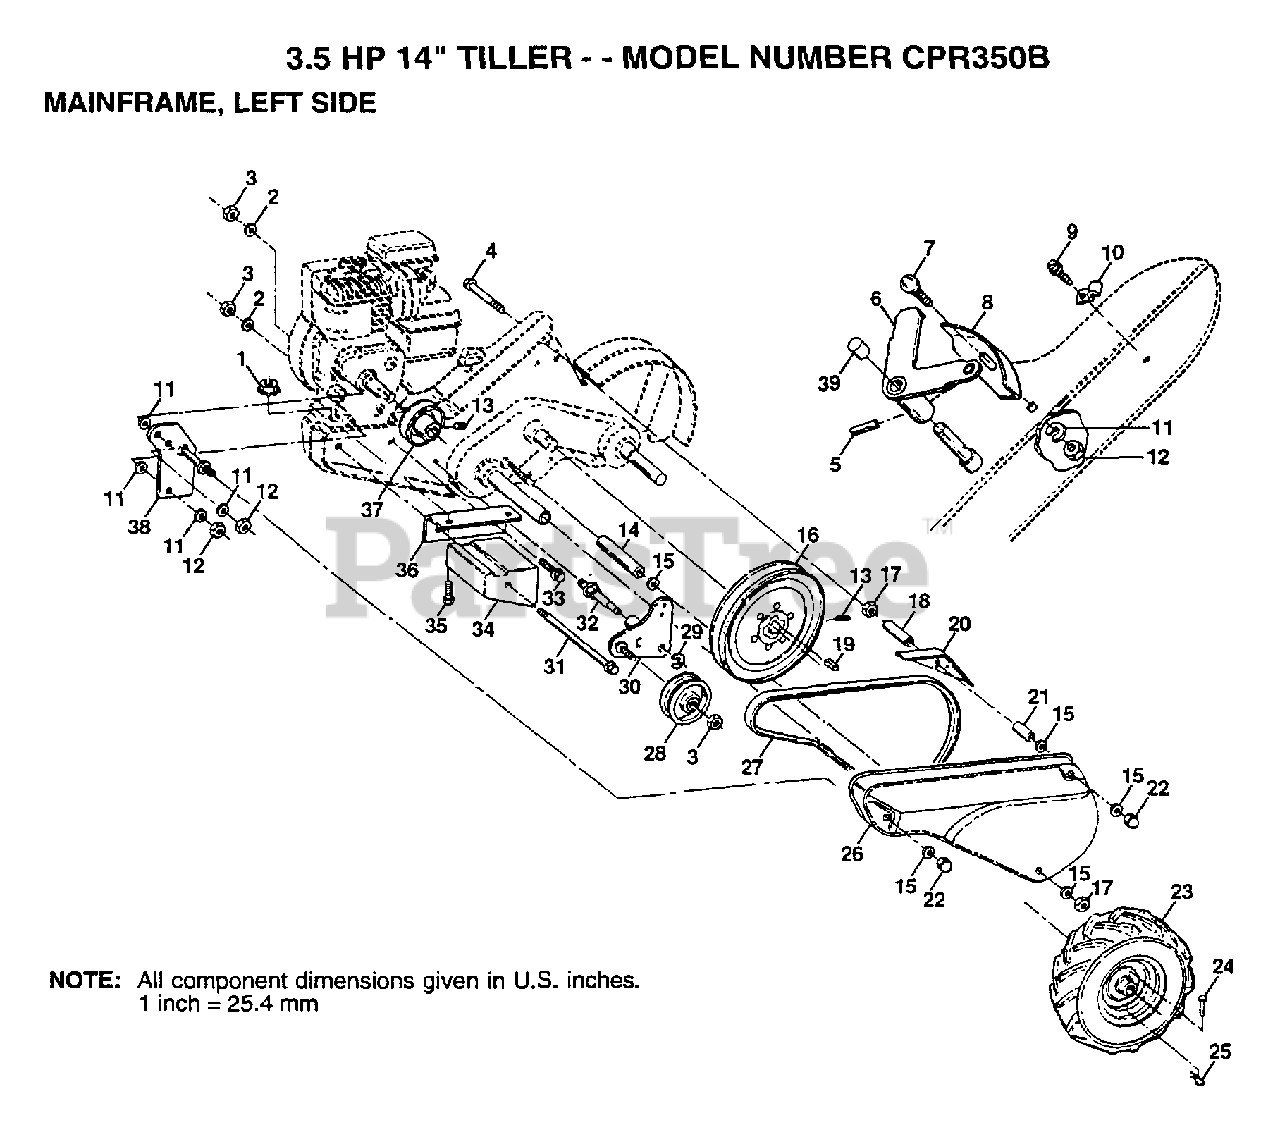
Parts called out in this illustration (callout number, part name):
2	LOCKWASHER
3	NUT.HEX.3/8-16UNC
4	BOLT TI
6	LEVER ASM CRT
7	BOLT
8	PANEL TI
10	CONDIUT CLIP T
11	LOCKWASHER
13	SET SCREW
14	SPACER
15	WASHER
16	"SHEAVE 10"" CRT"
17	NUT.HEX.5/16-18
18	SPACER CRT
19	KEY T
20	GUARD CRT
21	SPLIT SPACER
22	NUT TI
23	TIRE.CHV.13X5.0-6
24	RIVET.DRILL.1.75
25	RETAINER M
27	BELT-V
28	PULLEY-IDLER TI
29	KLIP RING
31	BOLT CRT
32	SHIFT ARM CRT
33	BOLT
34	COUNTERWEIGHT CRT
35	BOLT.HEX.5/16-1.5
36	BRACKET LH CRT
37	ENGINE SHEAVE
38	BELT GUARD BRKT
39	CAP PLUNGER BLACK
